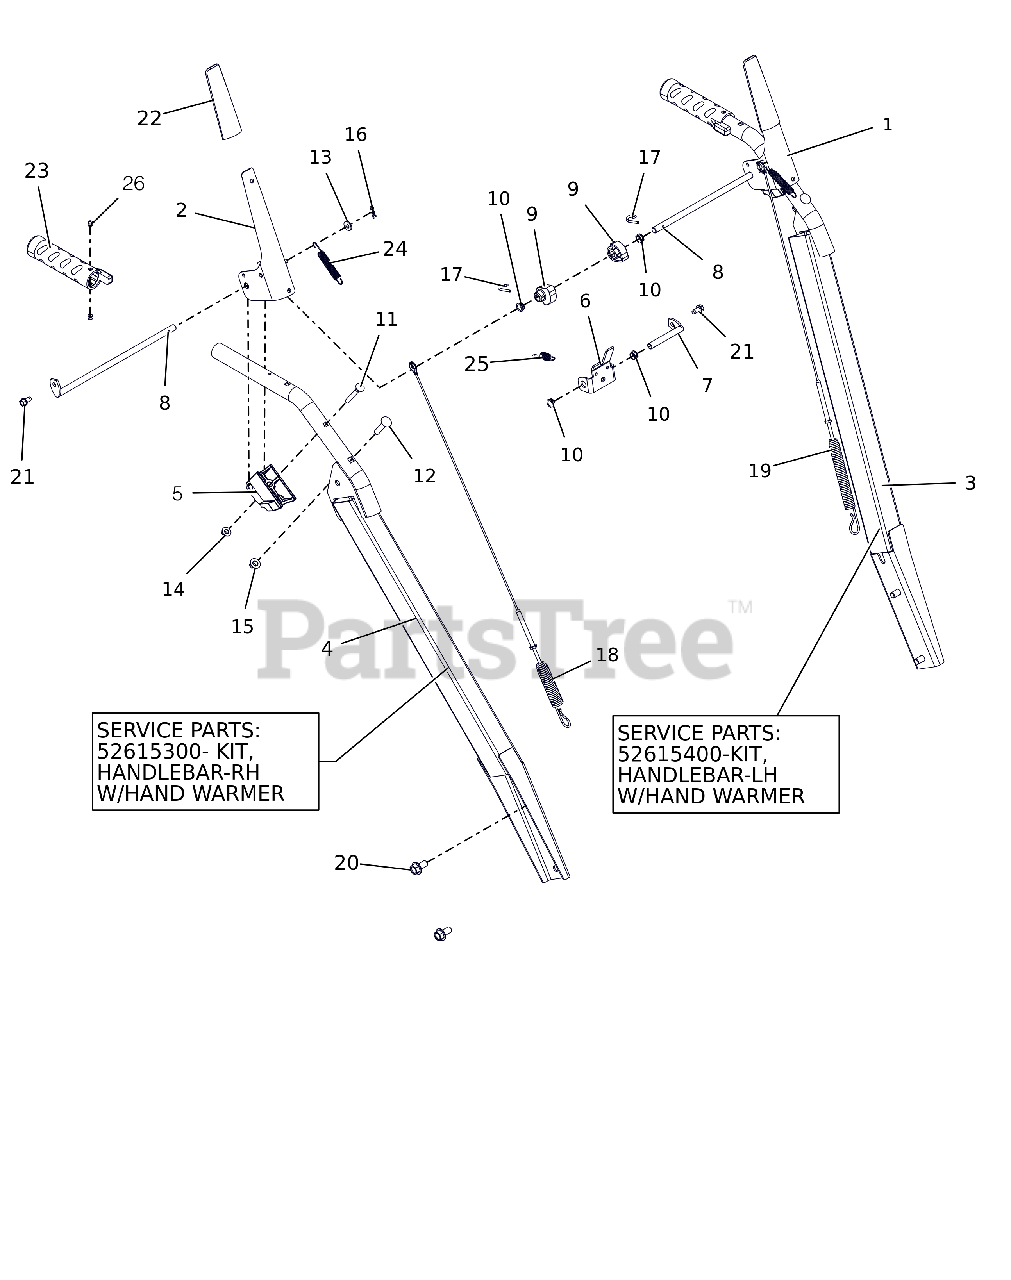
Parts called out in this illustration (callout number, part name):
1	LEVER, CLUTCH-LH
2	LEVER, CLUTCH-RH
3	HANDLEBAR, HEAVYDUTY-PRO LH
3	KIT, HANDLEBAR-LH W/WARM GRIP
4	HANDLEBAR, HEAVYDUTY-PRO-RH
4	KIT, HANDLEBAR-RH W/WARM GRIP
5	BLOCK, CLUTCH PADDLE
6	BRACKET, INTERLOCK ARM
7	ROD, PIVOT - INTERLOCK
8	ROD, PADDLE MOUNT - PRO
9	CAM, INTERLOCK
10	BUSHING, POLYLINER-.38 SNAPIN
11	BLT-RDHDXLSQNK .25-20X2.0 G5YZ
12	@BLT-RDHDSQNK .31-18X1.50 G5YZ
13	@WSHR-FL-STL.281X.62X.065 YWZC
14	@NUT-LK-CTR-FLG .25-20 YWZC
15	@NUT-LK-TOP-FLG .31-18 YWZC
16	PIN-HAIR INT .06X.18X.77
17	PIN, SPRING CLIP
18	CABLE, AUGER (DELUXE & PRO)
19	CABLE, UPPER TRACTION
20	BLT-SERHFWH .38-16X.75 YWZC
21	SCR-TAP .25-20X.50 HWH TR YWZ
22	SLEEVE, CLUTCH PADDLE-GRAY
23	GRIP,HEATED HANDLE-GRAY
24	SPRING, EXTENSION
25	SPRING-EXT .047X.438X1.45
26	RVT-POP #43 .125X.313 STL ZINC
